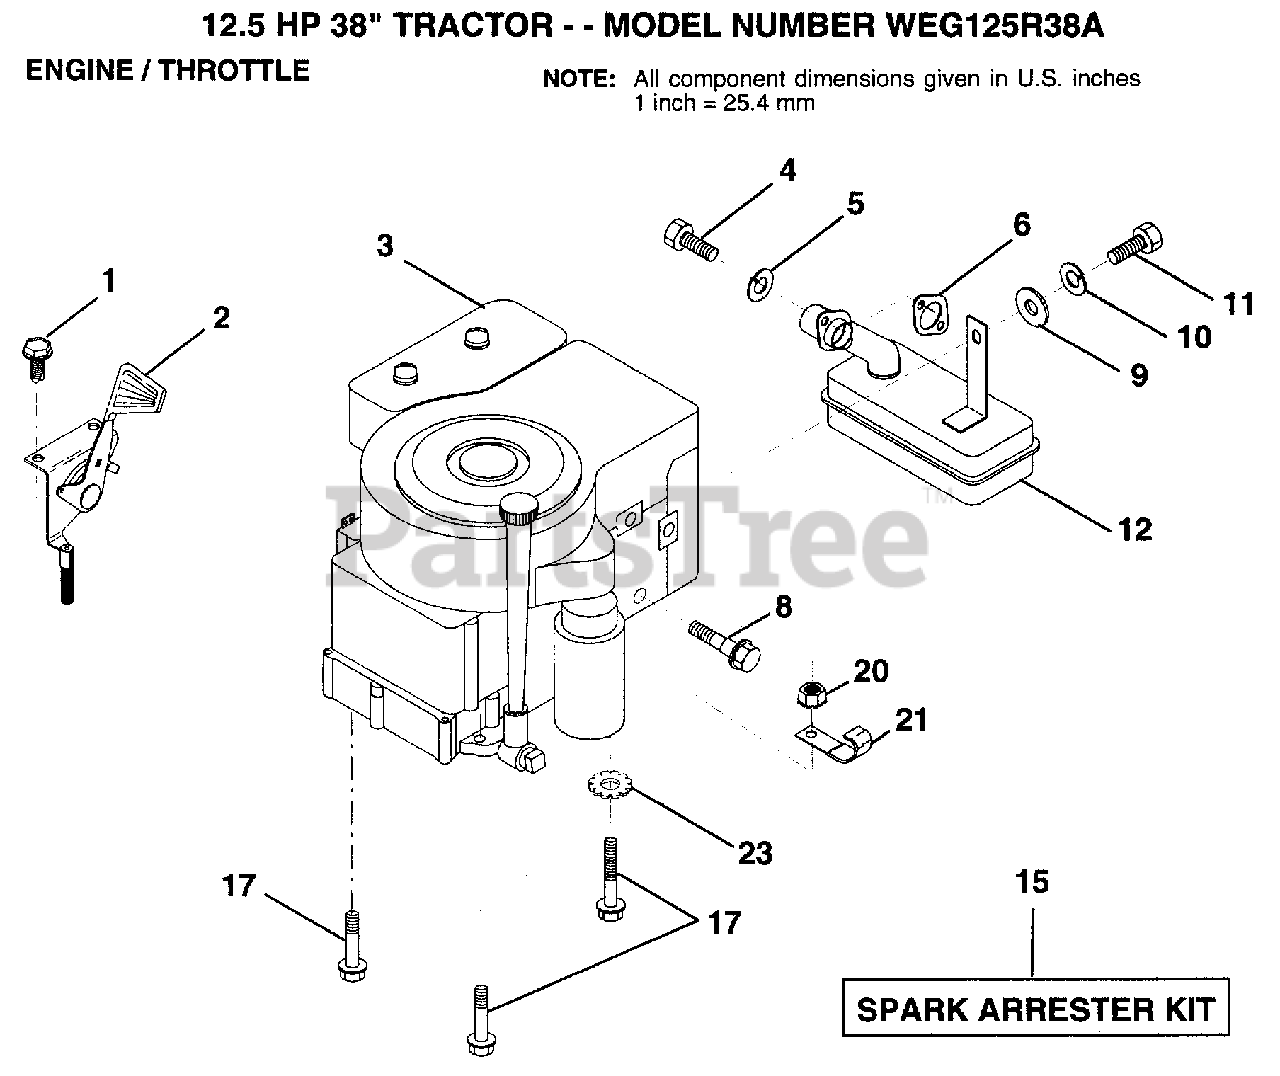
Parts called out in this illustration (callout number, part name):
1	SCREW.1/4-20X1/2
2	"CONTROL,THROTTLE"
4	SCREW
8	LOCKWASHER
8	BOLT T
10	LOCKWASHER
12	MUFFLER
17	SCREW LT
21	CLIP T
